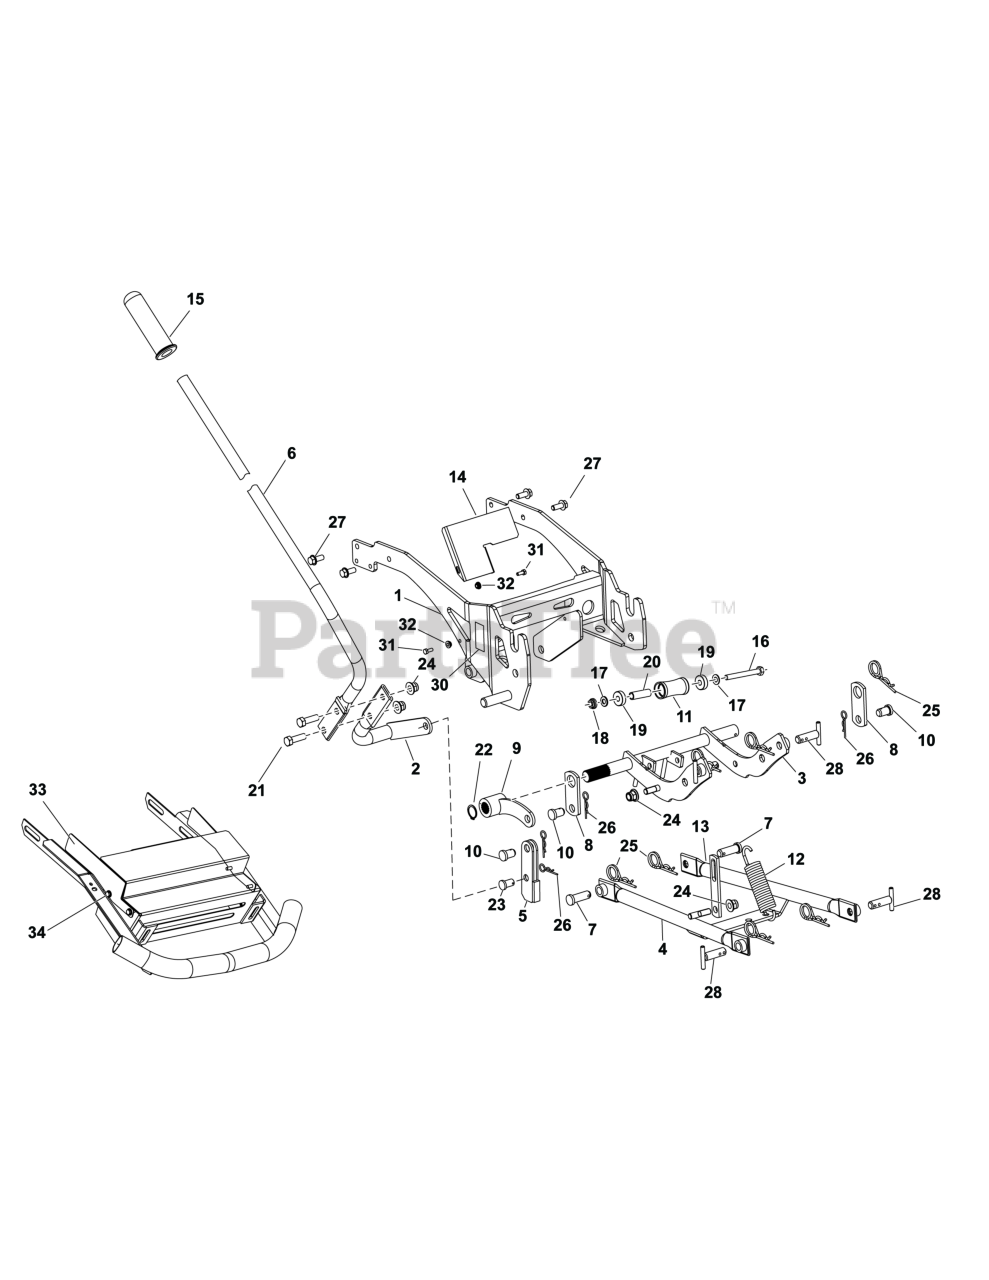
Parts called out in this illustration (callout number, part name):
1	CARRIER
6	LEVER ASSEMBLY
8	RETAINER
13	RETAINER
25	PIN, Cotter
